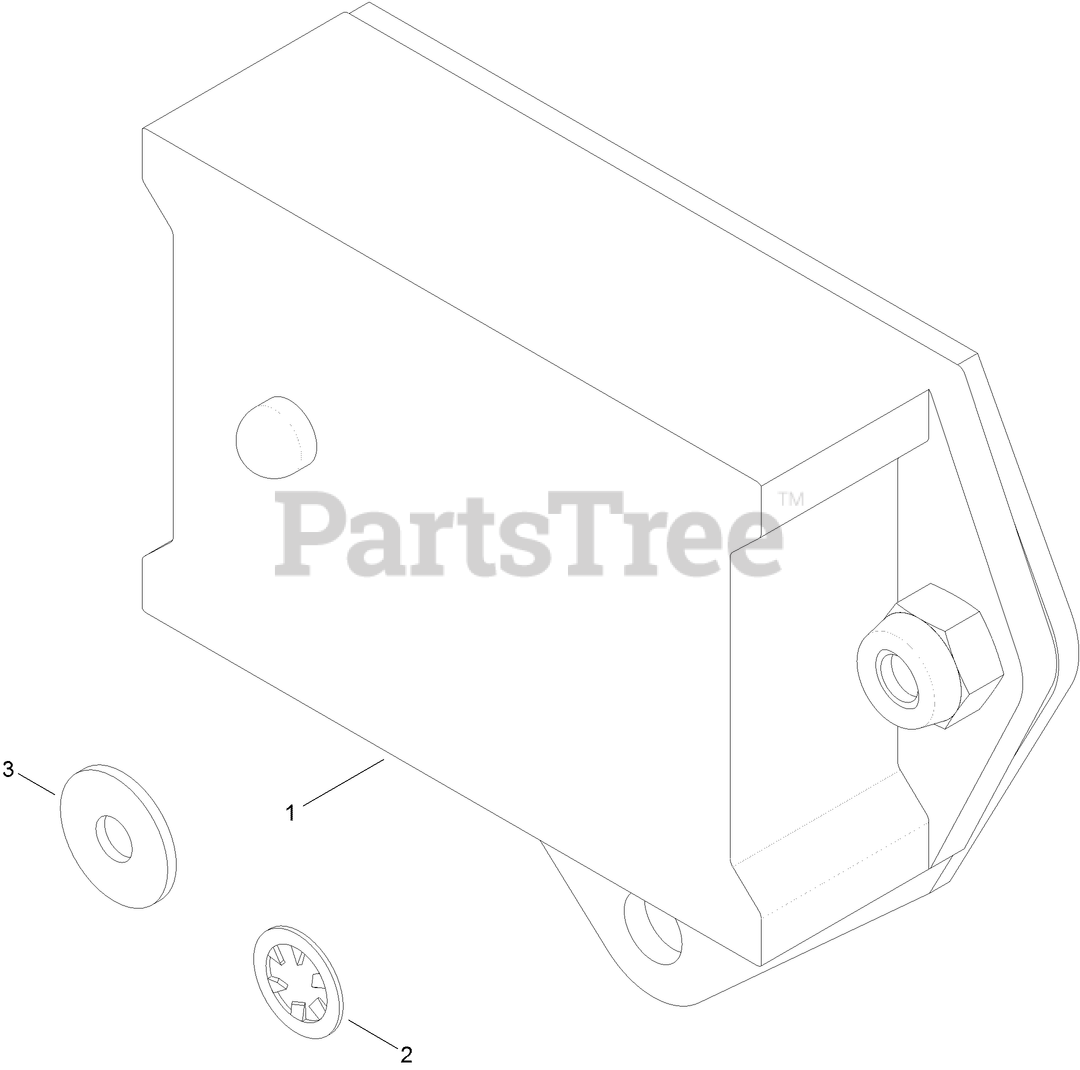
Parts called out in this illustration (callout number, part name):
1	SWITCH-TIP
2	WASHER-STAR
3	WASHER
